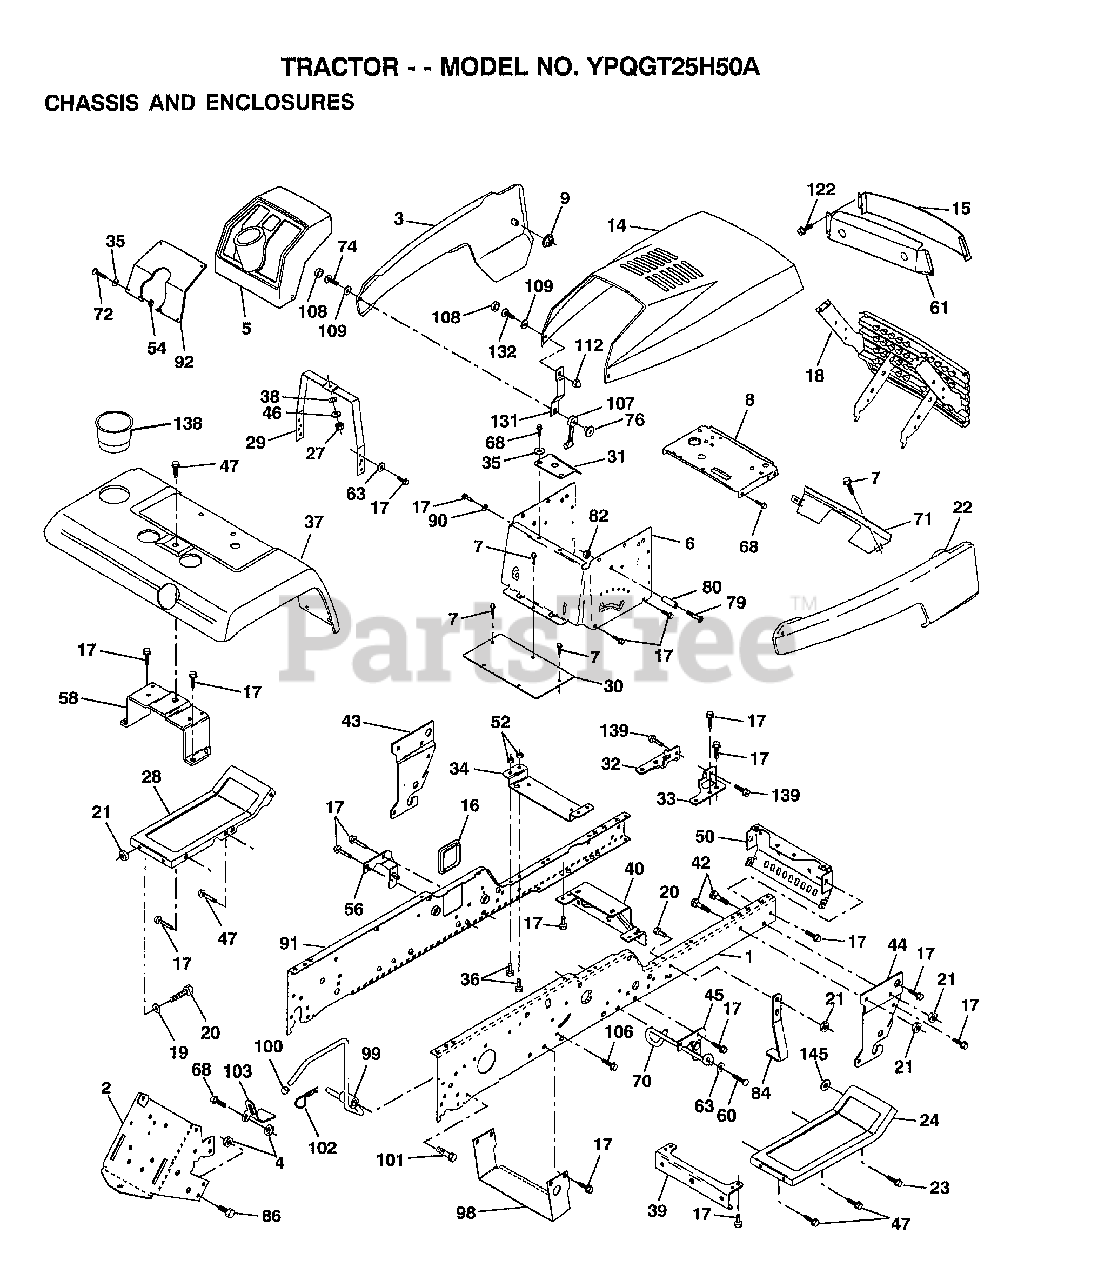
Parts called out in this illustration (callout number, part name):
1	"RAIL,FRAME RH"
2	DRAWBAR GT
3	"PANEL ASM-SIDE,LH"
4	NUT.7/16
5	DASHBOARD BLACK
6	DASH LOWER
7	SCREW
8	SUPPORT.DASH.BTRY
9	PAL NUT LT
14	"HOOD, YARD PRO"
15	LENS.BAR.CLEAR
16	COVER ACCESS
17	SCREW
19	WASHER
20	BOLT
23	SCREW
24	FOOTREST.RH.LT/GT
28	FOOTREST PNT LH
29	DASH.SUPT.YP/HUSQ
30	SADDLE.HYDRO.95
31	BRKT SUPT 1-PC VG
32	BKRT.PIVOT.CHASSIS.LH
33	BKRT.PIVOT.CHASSIS.RH
34	BRACKET.ENG.SUPT.
35	WASHER
36	BOLT
38	LOCKWASHER
39	BRACKET.AXLE.FRT.
40	"BRKT SUPPORT,AXLE"
43	BRACKET.SUS.FT.LH
44	BRACKET.SUS.FT.RH
45	BRACKET.SUSP.RH.
46	WASHER PM
47	SCREW LT
50	"BRKT CHASSIS,FRNT"
56	BRACKET.SUSP.LH.
58	BRKT.ASM.FENDER
60	SCREW
61	BEZEL.1 PC
63	WASHER
68	SCREW LT
70	GUIDE.BELT.MID.SP
72	SCREW
74	SCREW
76	WELDNUT
79	SCREW
80	SPACER LT
84	STOP.OVER.CENTER
86	BOLT
90	LOCKWASHER
91	"RAIL FRAME,LH"
92	PLATE.DASH.SLKS
98	BRACKET SKID CHAS
99	ROD BYPASS
101	SCREW LT
102	RETAINER M
103	LOCK BYPASS BRKT
107	HOOD LATCH T
108	SNAP CAP LT
109	WASHER LT
112	ACORN NUT RB
122	SCREW.HEX.WS.HD
131	BKT.SPT.HOOD/PANL
132	SCREW.10-24X3/8.
138	CUPHOLDER.YTGT
139	BOLT.SHOULDER.5/16-18
145	WASHER
